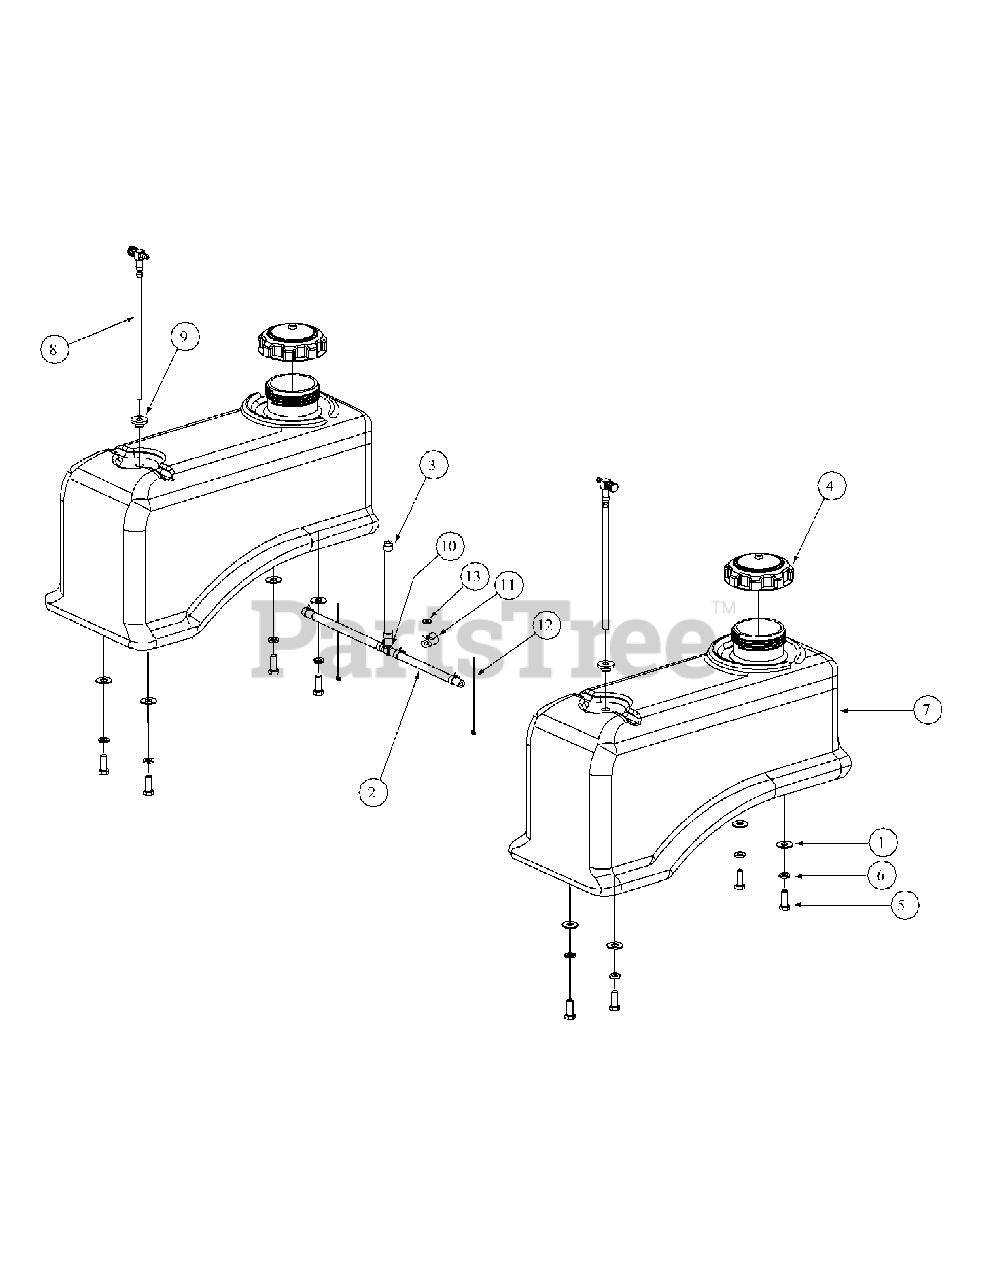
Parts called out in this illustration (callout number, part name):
1	Flat Washer, .406 ID, 1.0 OD, .105
2	Hose, 1/4" Fuel Line 79.5 inches
3	Clamp, Union
4	Fuel Cap, 3.5
5	Hex, Cap Screw, 3/8-16, .88
6	Lock Washer, 3/8
7	Fuel Tank
8	Fuel Fitting
9	Grommet, Fuel Tank
10	Tee Fitting, Fuel
11	Clamp, 1/2 Tubing
12	Cable Tie
13	Flat Washer, 1.4 x .630 x .0515
